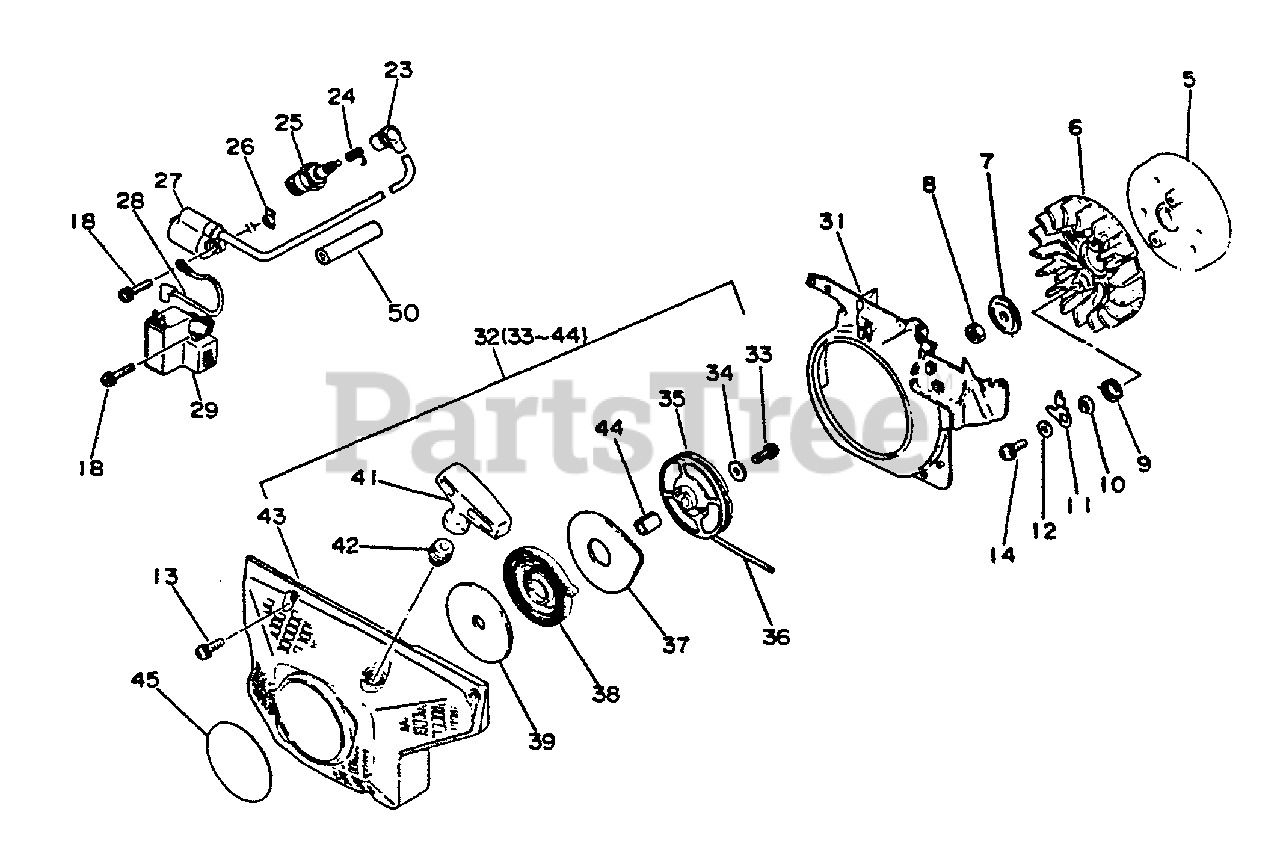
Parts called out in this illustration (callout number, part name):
5	FLYWHEEL
6	FAN
7	WASHER - CUP
9	SPRING, RETURN
10	SPACER
11	PAWL, STARTER
12	WASHER - 5
13	SCREW - 5X20
14	SCREW - 5X25
18	SCREW - 4X20
23	CAP, SPARK PLUG
24	TERMINAL, SPARK PLUG CAP
25	SPARK PLUG -- CJ-6Y
27	COIL, IGNITION
29	COIL, IGNITION
31	SHIELD, FAN
32	STARTER ASSY
33	SCREW - 5X14
34	WASHER - 5
35	REEL, ROPE
36	ROPE, STARTER - 4X950
37	PLATE, STARTER
38	SPRING, REWIND
39	PLATE, STARTER
41	GRIP, STARTER
42	GUIDE, ROPE
43	CASE, STARTER
45	LABEL - ECHO
50	TUBE
